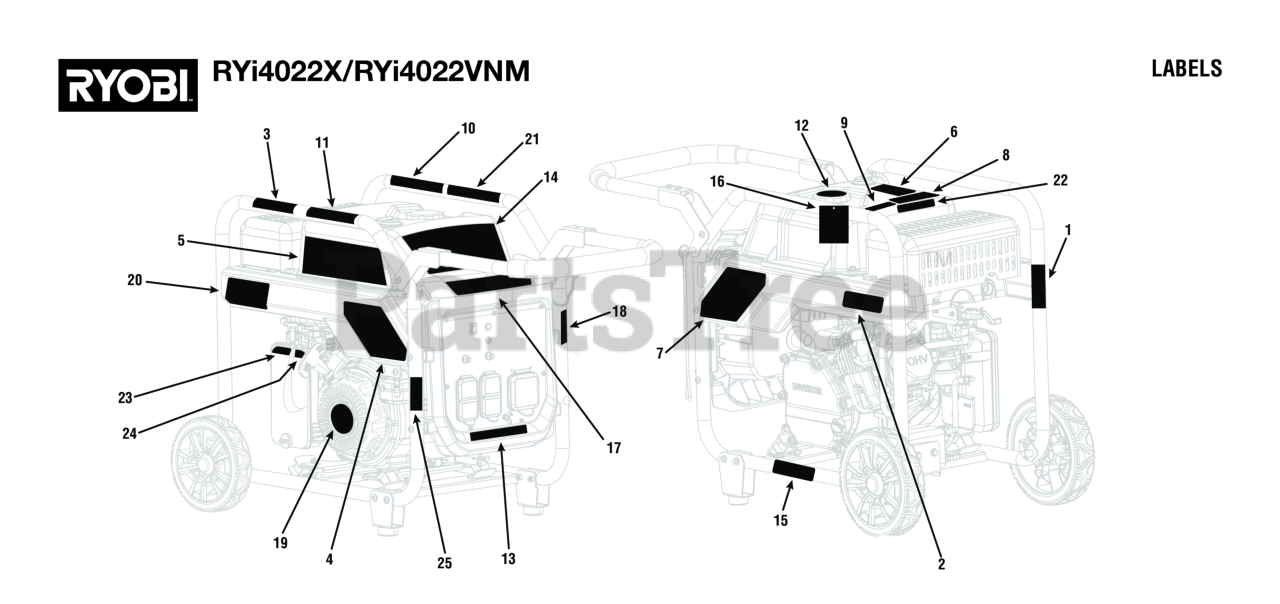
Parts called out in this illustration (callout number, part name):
1	Hot Surface Label
2	Inquires Label (Ryobi)
3	Combustion Label
4	Monitoring System Label
5	Co Instruction & Warning Label
6	CPSC Danger Label
7	Danger Icon Label
8	No E85 Label
9	Exhaust Direction Label
10	Fire Distance Label (Eng/Sp)
11	Risk of Fire Danger Label
12	Remove Cap Fuel Stabilizer Label (English)
13	Ground Warning Label (English/French)
14	Tank Logo Label
15	Engine Lubricant Label
16	Warning Hangtag
17	Performance Label
18	Locking Pin Label
19	Engine Recoil Label
20	Start Label
21	Fuel Stabilizer Label (Fr/Sp)
22	Hot Surface Label
23	Off Label
25	Do Not Tamper Label (FR)
